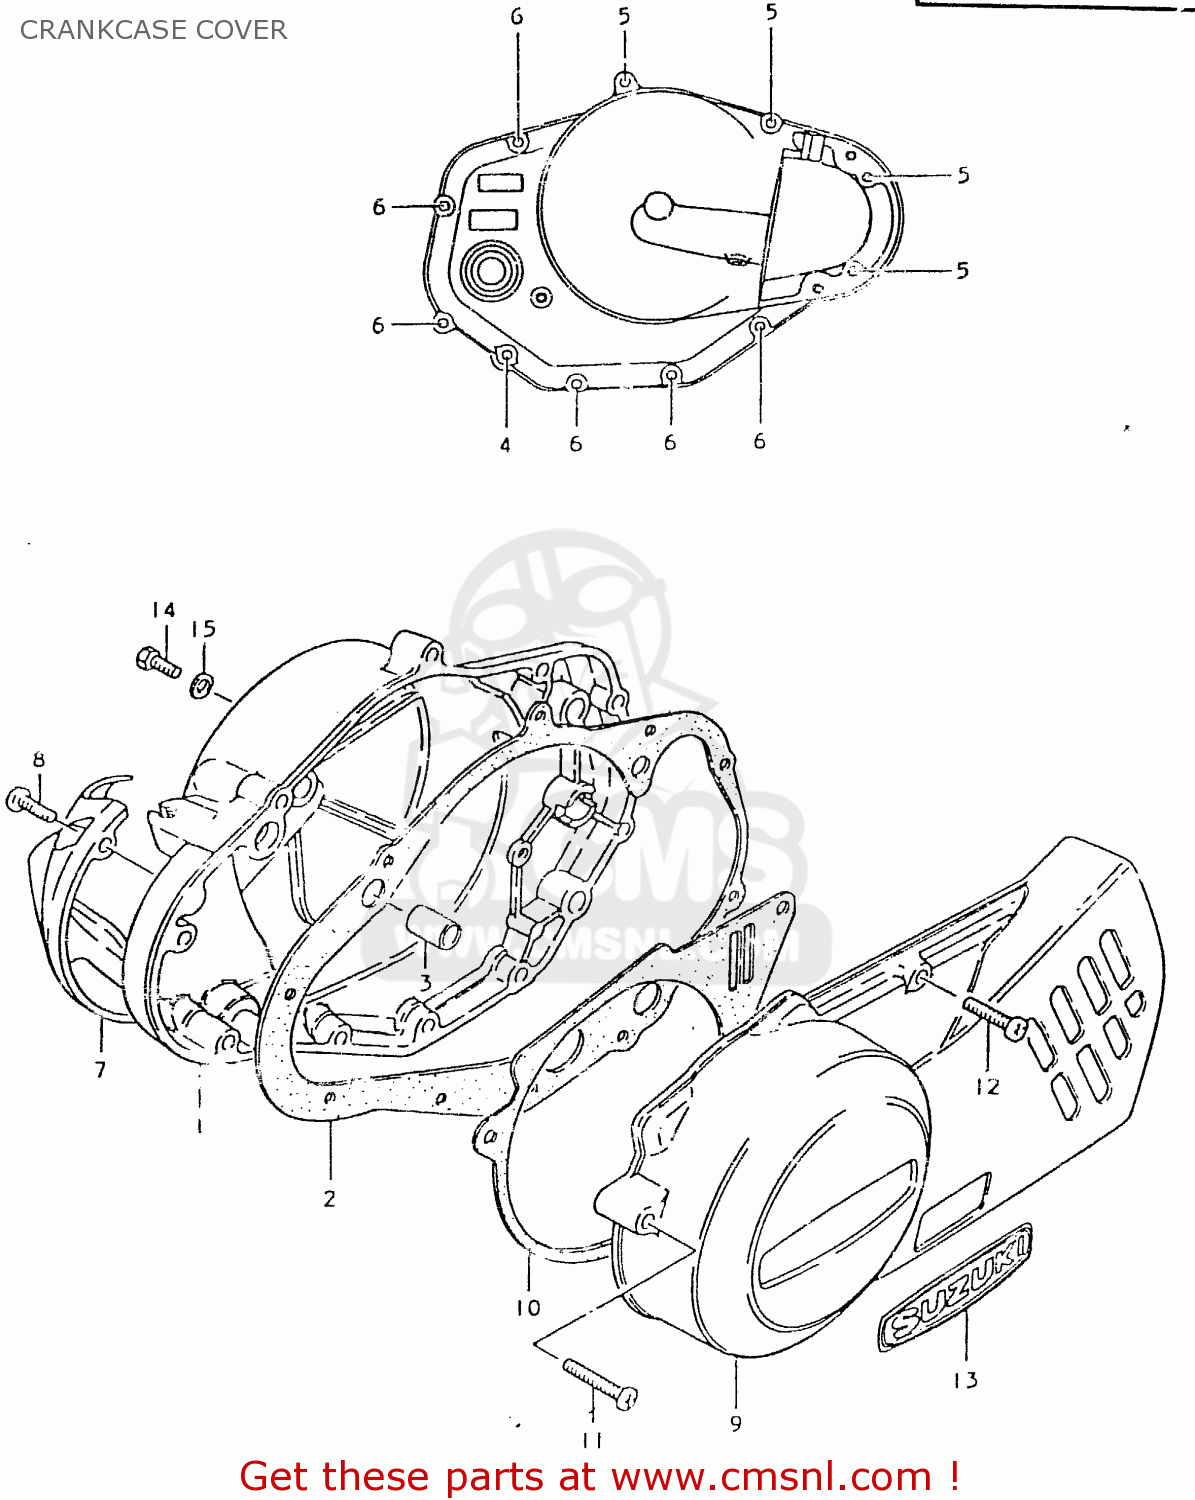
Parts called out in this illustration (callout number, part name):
1	COVER,CLUTCH
2	GASKET,CLUTCH COVER (MCA)
3	PIN
4	SCREW (6X45)
5	SCREW 6X30
6	SCREW
7	COVER,CLUTCH RELEASE ARM
8	SCREW
9	COVER,MAGNETO
10	GASKET,MAGNETO COVER (NAS)
11	SCREW 6X30
12	SCREW
13	EMBLEM,GENERATOR COVER
14	SCREW(6X10)
15	GASKET(6.2X11X1) (NAS)
